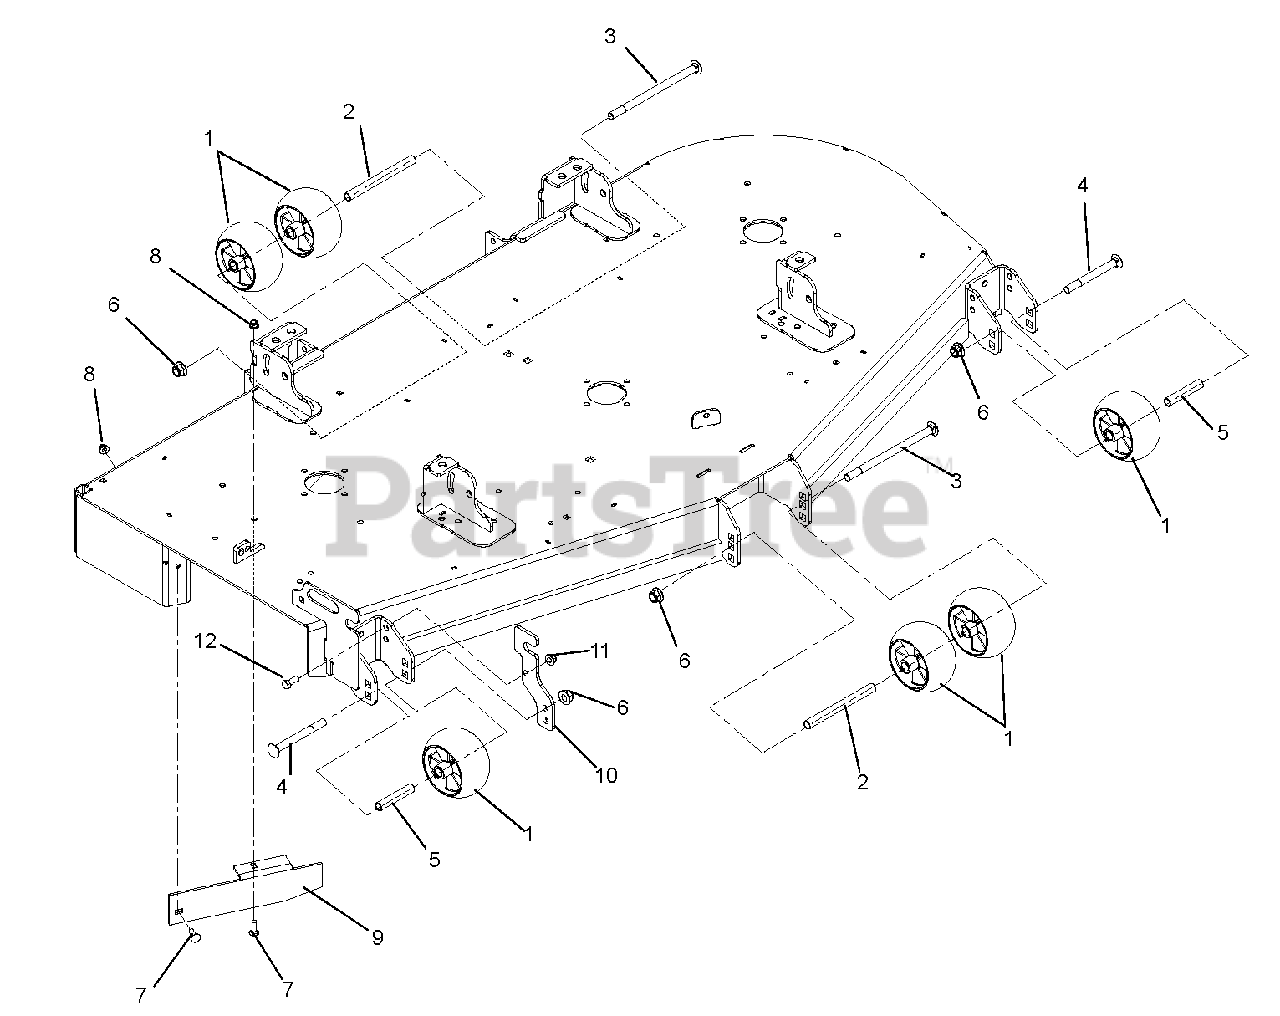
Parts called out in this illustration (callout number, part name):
1	Anti-Scalp Wheel, 5 x 3 Center
2	Spacer, .510 x .625 x 6.70
3	Bolt, Round Head Square Neck .50-13 x 8.50
4	Bolt, Round Head Square Neck .50-13 x 5.00
5	Spacer, .510 x .625 x 3.35
6	Nut, Locking-Nylon-Flange .50-13
7	Bolt, Round Head Square Neck .31-18 x 1.00 Grade 5
8	Nut, Locking-Nylon-Flange .31-18
9	52"Discharge Baffle
10	Bracket, Chute Storage
11	Nut, Locking-Nylon-Flange .38-16
12	Bolt, Hex .38-16 x 1.00 Grade 5
